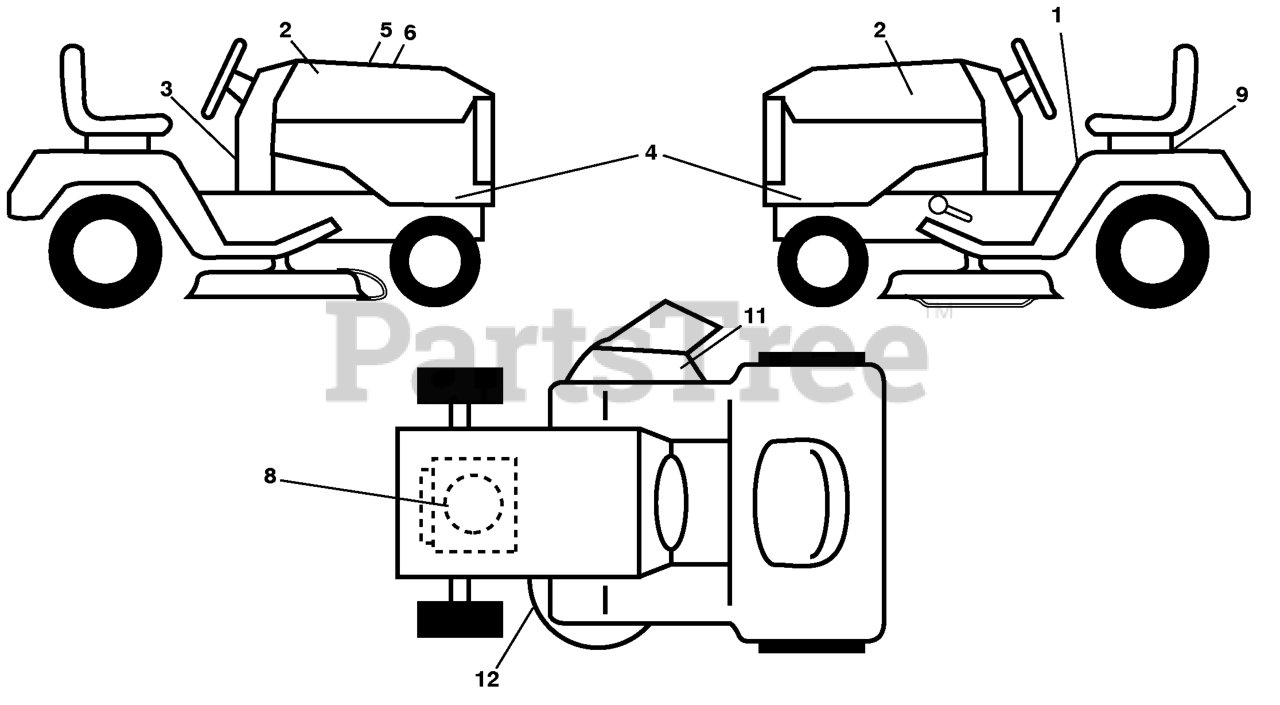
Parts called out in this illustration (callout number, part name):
1	DECAL.FENDER.WARNING.ENG
2	RP.DECAL.BADGE.170MM.TEXTLOGO
3	DECAL, WARNING SPARK ARRESTOR
4	DECAL PANEL SIDE
5	DECAL.WARNING.CUST.RESP.E85.
6	Decal, Replacement
8	DECAL.ENG.BS.20HPXRD.SL.278416
9	DECAL BTRY SYMBOLS
11	DECAL.WARN.KEEP.HAND.AWAY
12	DECAL V BELT SCHEMATIC
